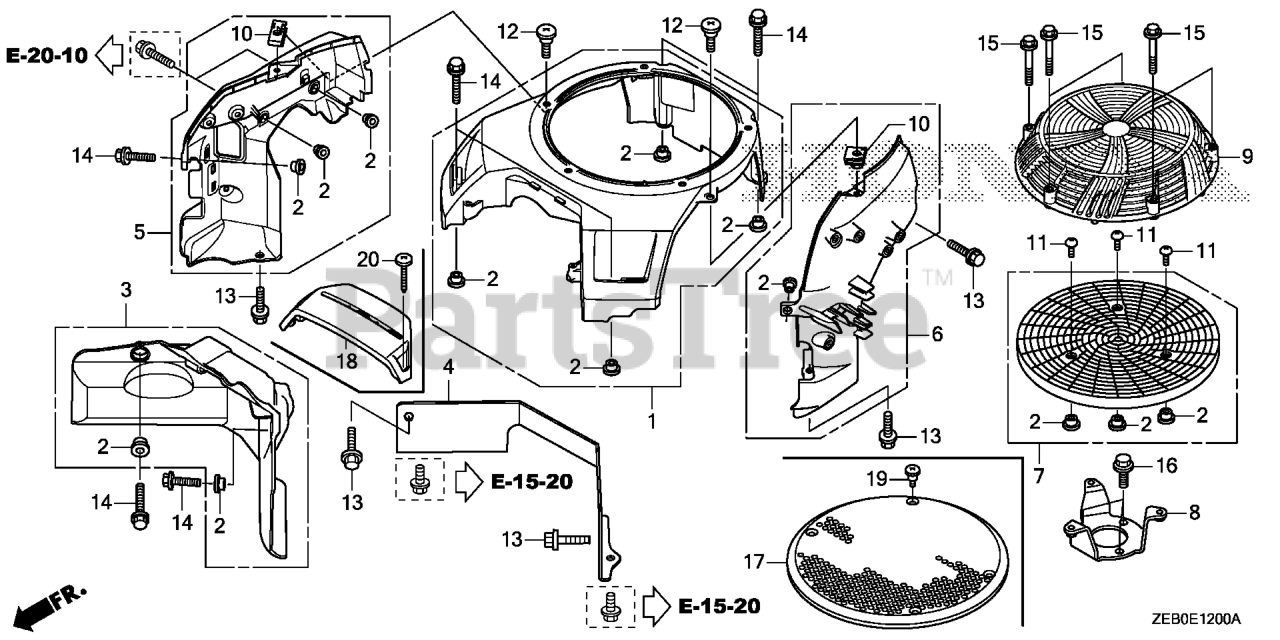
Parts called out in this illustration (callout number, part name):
1	COVER, FAN *R280* (POWER RED)
1	COVER, FAN *NH1* (BLACK)
2	COLLAR, FAN COVER
3	SHROUD (UPPER)
4	SHROUD B (UPPER)
5	SHROUD, R. (LOWER)
6	SHROUD, L. (LOWER)
7	GRID, SCREEN
8	HOLDER, SCREEN GRID
9	COVER, SCREEN GRID
10	NUT, FENDER SETTING
11	SCREW, TRUSS (6X16)
12	SCREW, SPECIAL (6X15)
13	BOLT, FLANGE (6X16) Use from Engine SN 2056820.
14	BOLT, FLANGE (6X20)
15	BOLT, FLANGE (6X40)
16	BOLT, FLANGE (8X18) Use from Frame SN 1256673.
